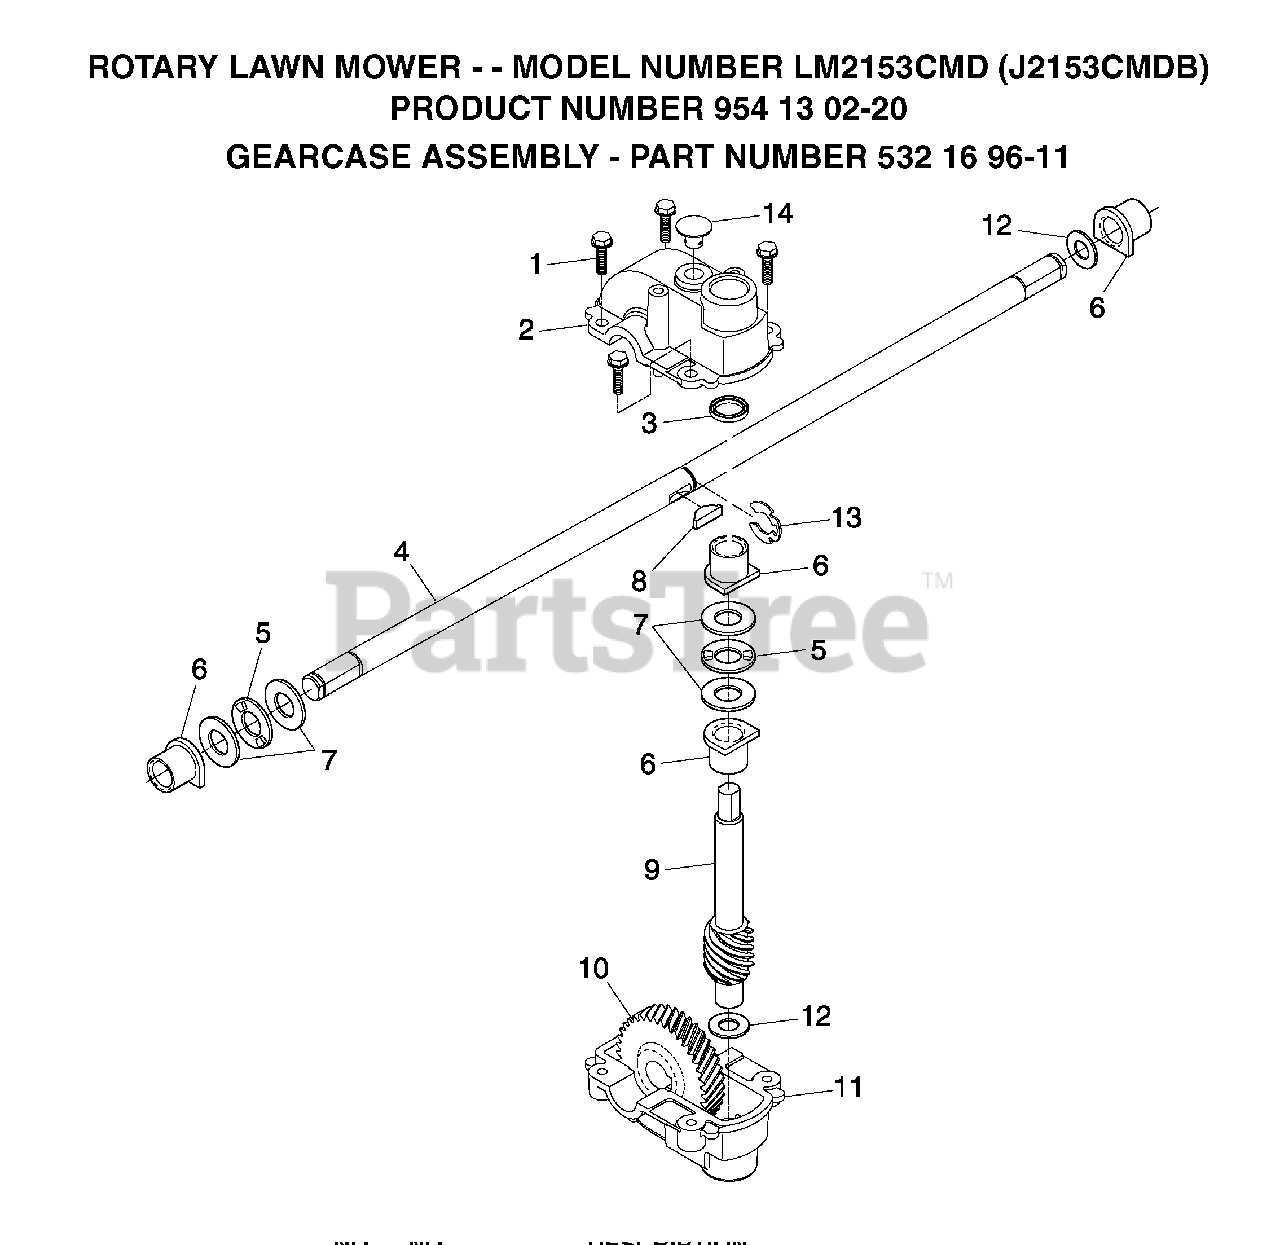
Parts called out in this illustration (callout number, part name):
2	GEAR CASE, UPPER
4	TRANSMISSION ASM. (WALK)
5	BEARING, NEEDLE, THRUST
7	WASHER, THRUST
8	HI PRO KEY
9	SHAFT GEAR WORM
10	GEAR, HELICAL
11	GEAR CASE, LOWER
12	THRUST WASHER
13	KLIP RING
